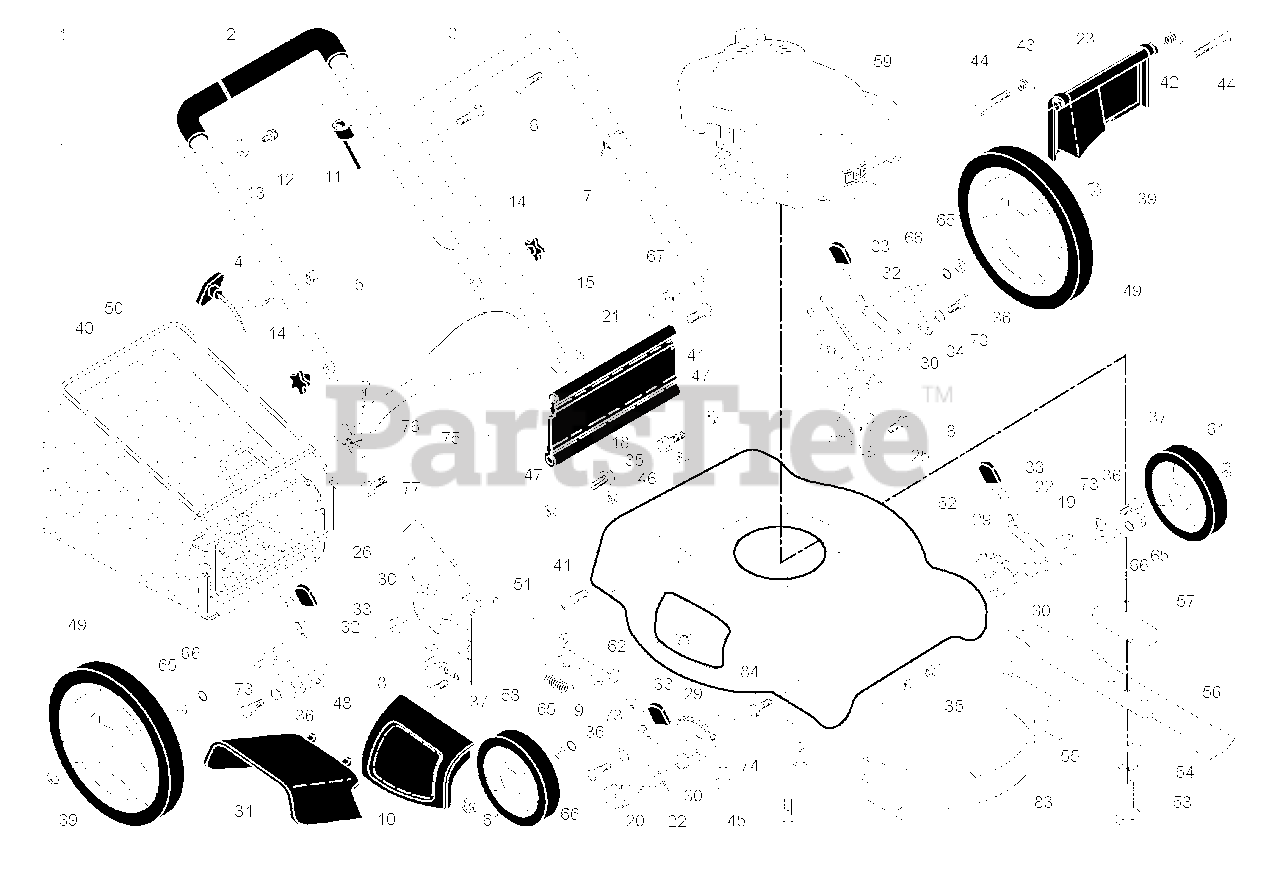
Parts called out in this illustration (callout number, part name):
1	CONTROL BAR
2	HANDLE.UPPER.W/GRIP.FGD/PUSH
3	HANDLE.LOWER.D-STRAIT.GREY
4	RB GUIDE.ROPE.STD.BLK.ZIN WSL
5	NUT
6	BOLT, HANDLE 5/16-18X1.75
7	TIE GUIDE
8	BOLT
9	BRACKET.ASM.HOUSING.EZ.MUL
10	RP DOOR.MULCH.21".REAR.PUSH.GR
11	CABLE.MZR.PUSH.HONDA.STRT
13	BRACKET.UPSTOP.RT
14	KNOB.HANDLE.PLASTIC.STAR.BLACK
15	HAIRPIN COTTER
18	SCREW 1/4X20
19	AXLE ARM ASSY FRONT LH
20	AXLE ARM ASSY FRONT RH
21	RP_KIT.SKIRT.21 DOMED.W/LIP
22	SELECTOR SPRING, FRONT
23	REAR DOOR ASSY
25	RP BRACKET.ASM.HND.HW.21.LT.
26	RP BRACKET.ASM.HAND.HW.21.RT.O
29	WHEEL ADJ BRACKET FRONT
30	SPACER.HEIGHT.ADJUSTER(2 2)3 2
31	DEFLECTOR.CLIPPING.21.GREY
32	SPRING.SEL.EXT.21.DOMED.12/14
34	AXLE ARM ASSY REAR LH
35	NUT.FLANGE.HEX.5/16X18.BLACK
36	SHOULDER BOLT 5/16-18
37	WHEEL & TIRES ASSY, FRONT
39	NUT.HEX.FLANGE.3/8-16.LOCKNUT
40	FRAME.BAG.21.REAR.DOMED.PUSH
41	SCREW.1/4-20X21/4.HEX.
42	SPRING.LH.22.REAR.DOOR.EZ.EMPT
43	SPRING.RH.22.REAR.DOOR.EZ.
45	BOLT 3/8-16X1-1/8
46	DANGER DECAL
47	NUT.LOCK.5/16-18
48	AXLE ARM ASSY REAR RH
49	WHEEL ASSY
50	GBAG.2323247.SILVER
51	ROD.HINGE.COMBI-C
52	HOUSING.21.MC.DOME.ORG.ENG.
53	SCREW, HEX HD 3/8-24 X 1-3/8
54	LOCKWASHER
55	WASHER,HARDEN
56	BLADE.21.PUSH/RWGD/FWGD
57	ADAPTER.BLADE.W/KEY.25MM.CE
58	TORSION SPRING
61	NUT.HEX.FLANGE.3/8-16.LO(3 2)
62	LOCKNUT.NYLOC.1/4-20
66	O-RING..070X.487.NEOPRENE
67	CLIP.CABLE.BLK
73	WASHER.CURVED.CYLINDRICAL
74	WASHER.ENGINE.BZP
75	KIT.BAFFLE.REAR.PLASTIC.21.RD
76	BAFFLE.REAR.PLASTIC.21.RD.ECON
77	SCREW.HX.13X.750
83	BAFFLE.FRONT.21.DOME.US
84	BOLT.5/16HEX.WHS.HD
